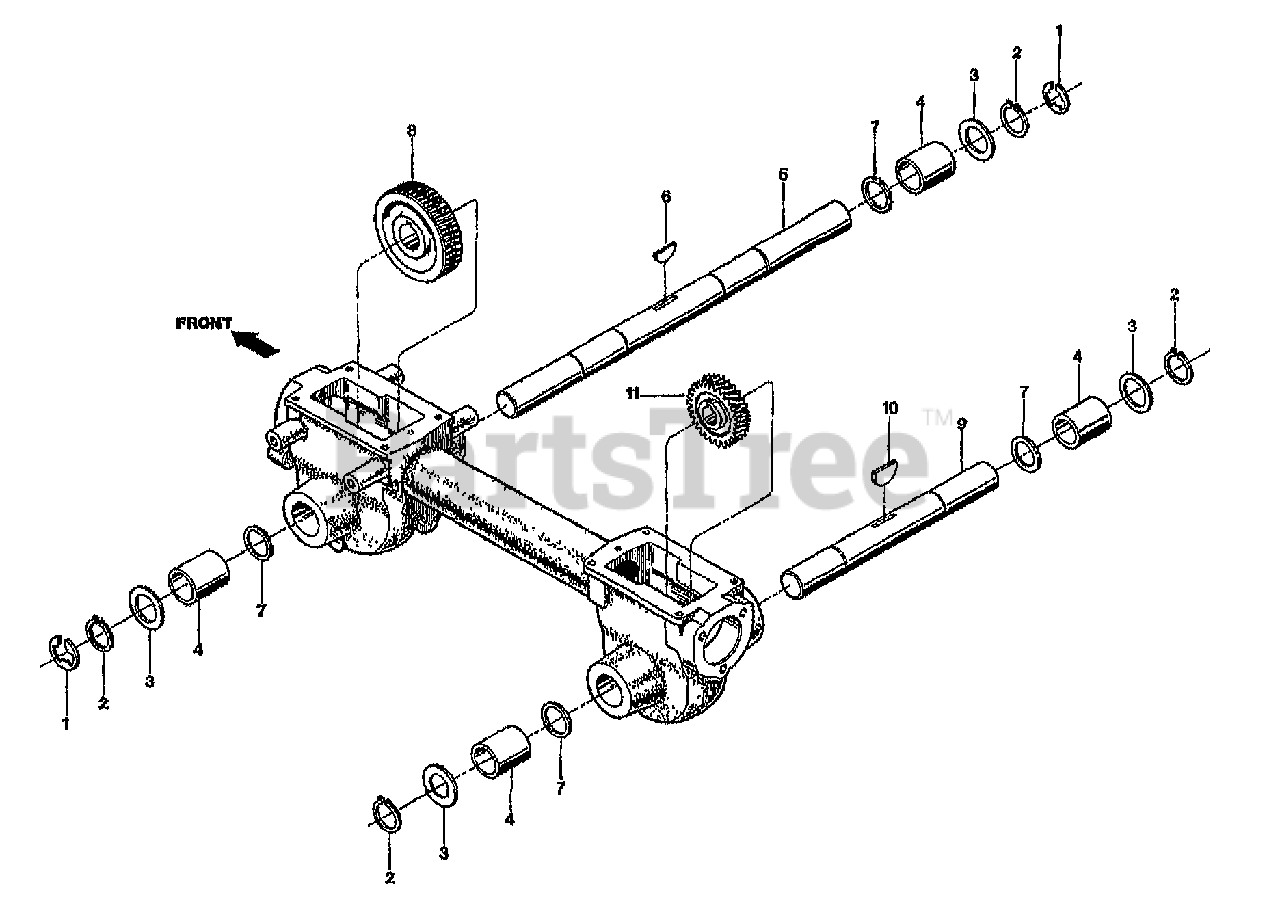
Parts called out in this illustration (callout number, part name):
1	RING-RETAINING 5133-989
2	RING-HEAVY EXT .906 ID
3	SHIM-1.375X1.015X.062
3	SHIM-1.375X1.015X.03
3	SHIM-1.375X1.015X.015
3	SHIM-1.375X1.015X.01
3	SHIM-1.375X1.015X.005
4	BUSHING-1.25X1.005X1.5
5	SHAFT-WHEEL MACH
6	KEY-HI PRO .25X1.062
7	SHIM-1.234X1.015X.062
8	GEAR-WORM 61 TEETH MACH
9	SHAFT-TILLER MACH
9	SHAFT-TUFFY TLR MACH {12155}
10	KEY-WOODRUFF .25X1.12
11	GEAR-WORM BRONZE MACH
11	GEAR-WORM TINE MACH {12155}
